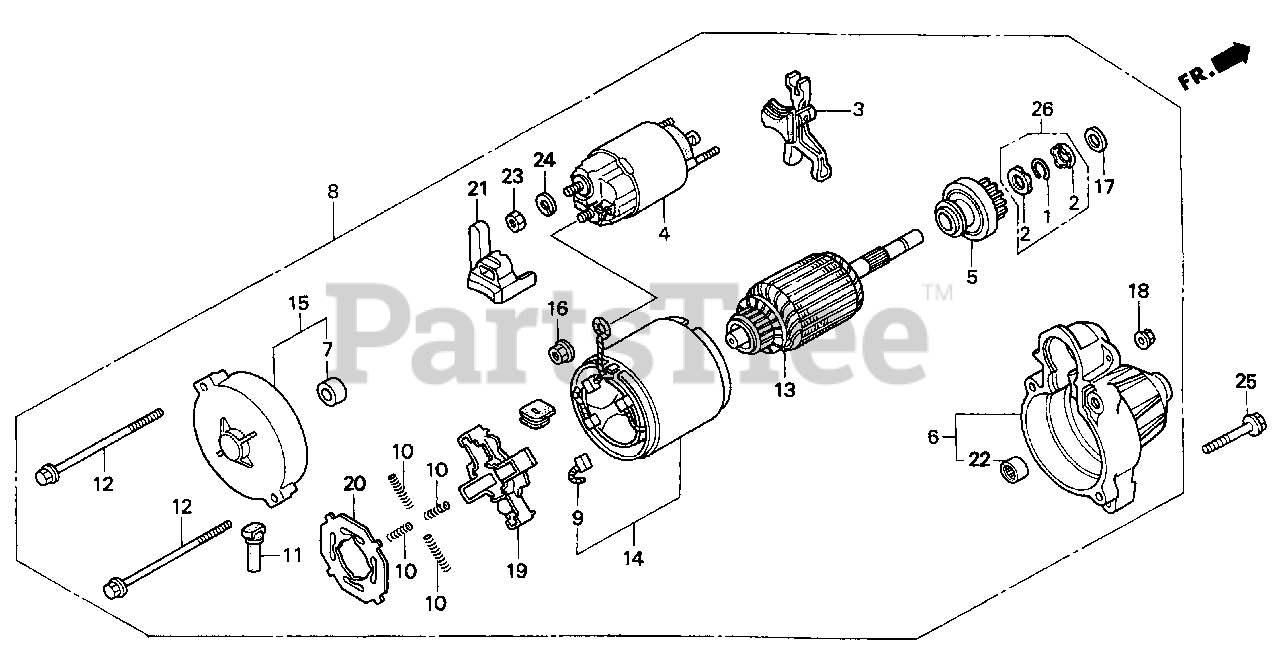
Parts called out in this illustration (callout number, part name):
1	RING, SNAP (DENSO)
3	LEVER, PINION DRIVE
4	SWITCH ASSY., MAGNETIC
5	CLUTCH, OVERRUNNING
6	HOUSING, SIDE DRIVE
8	MOTOR ASSY., STARTER
10	SPRING, BRUSH
11	COVER, RR.
12	BOLT, THROUGH
15	FRAME, COMMUTATOR END
16	NUT, HEX. (8MM)
18	NUT, FLANGE (5MM)
19	HOLDER, BRUSH
20	INSULATOR, BRUSH HOLDER
21	COVER, TERMINAL
23	NUT, HEX. (8MM)
24	WASHER, SPRING (8MM)
25	BOLT, FLANGE (8X40)
26	COLLAR SET, CLUTCH STOP
